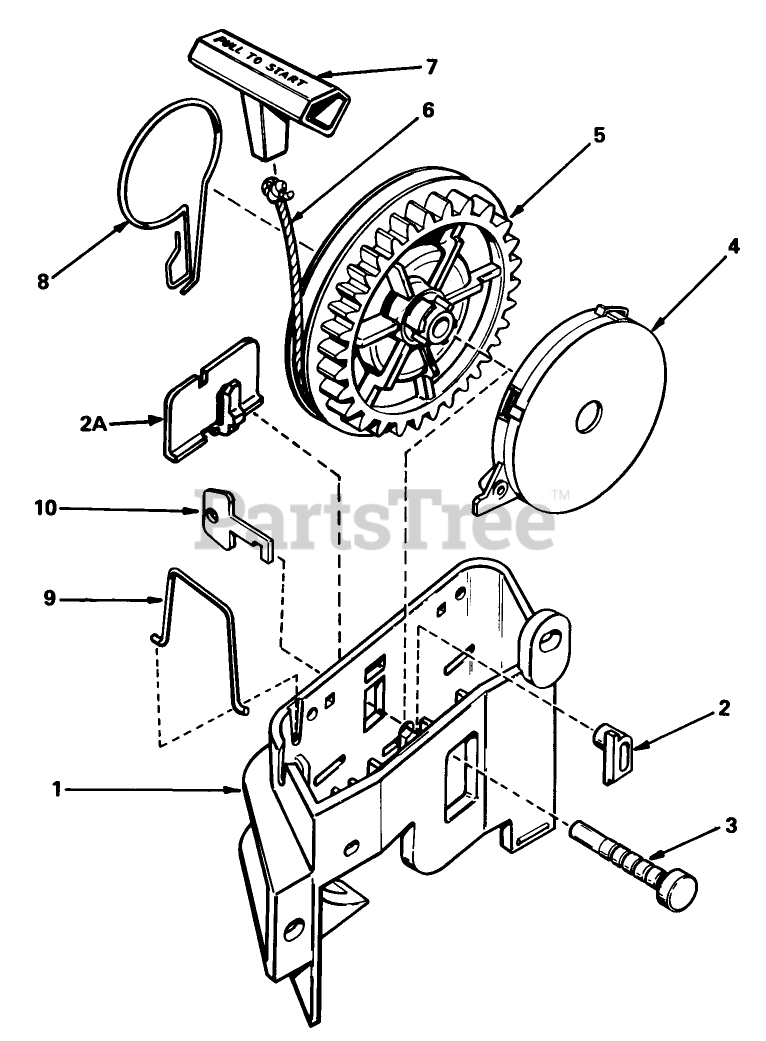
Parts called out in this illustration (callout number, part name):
1	Bracket Starter
2	Pawl, Locking Not used on all engine models)
2A	Clip, Starter Bracket (Used On Starters Not Equipped With Pawl, Ref. No. 2)
3	Pin-Pulley
4	Spring Assy., Rewind (Incl. Ref. #3)
5	Pulley
6	Rope Starter (Length 65" 9/64" Dia.)
7	Handle-Starter
8	Brake
9	Clip-Rope
10	Key (Not Used On All Engine Models
